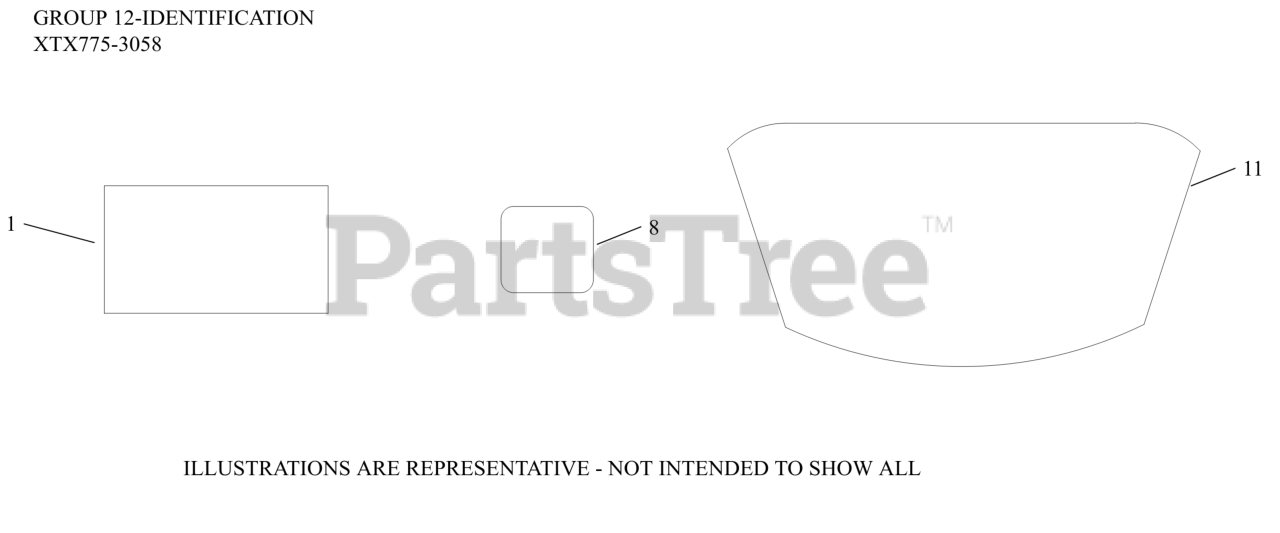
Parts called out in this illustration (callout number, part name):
1	DECAL, WARNING
8	DECAL, ON/OFF COURAGE XT7 (TTI)
11	LABEL, XTX775
